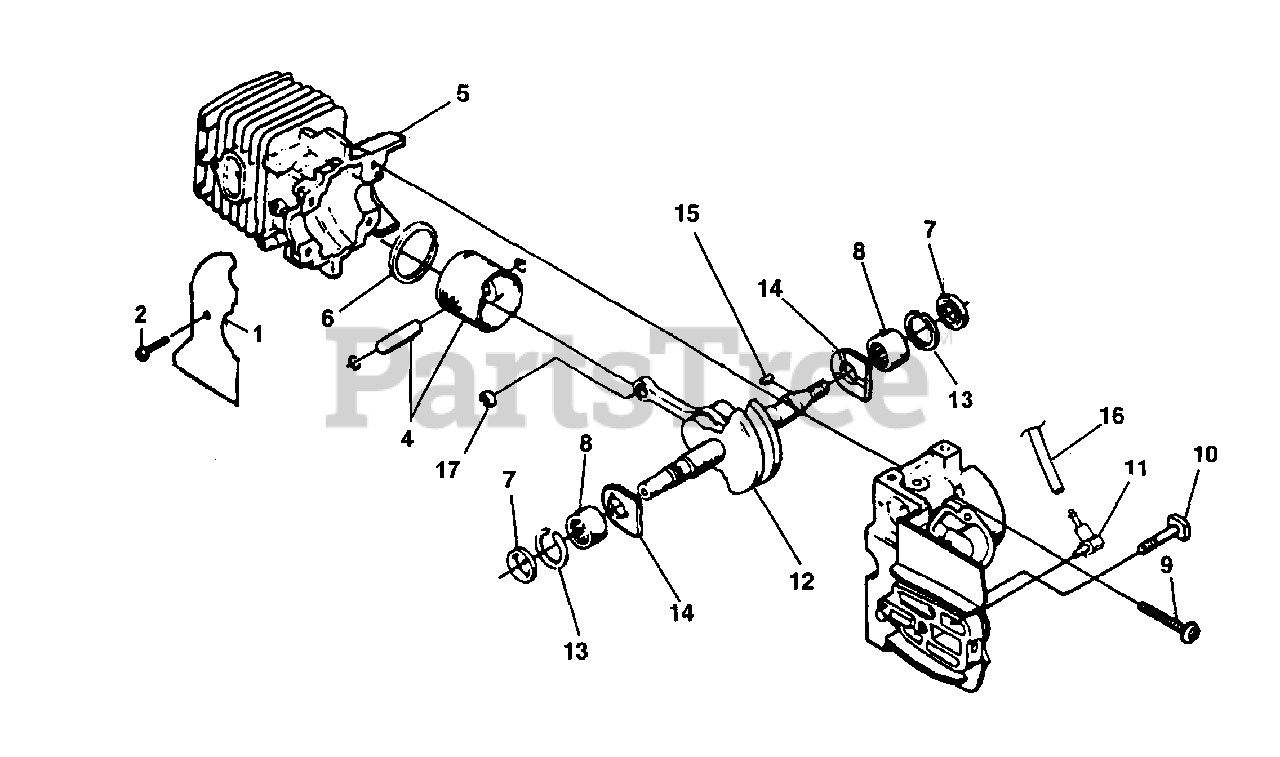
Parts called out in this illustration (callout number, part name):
1	SAW DUST SHIELD
2	SCREW, SELFTAPPING (#6 x 5/16")
3	SHORT BLOCK
4	PISTON & PIN ASSY.
5	CYLINDER
6	RING, PISTON
7	SEAL, SHAFT
8	BEARING, NEEDLE
9	SCREW,TORX PAN HEAD (10-24 x 1-1/8")
10	BOLT, GUIDE BAR
11	VALVE, CHECK
12	CRANKSHAFT, ROD & BEARING
13	SPACER
14	WASHER, THRUST
15	KEY, WOODRUFF
16	TUBING, RUBBER OIL LINE (8")
17	BEARING, WRIST PIN
